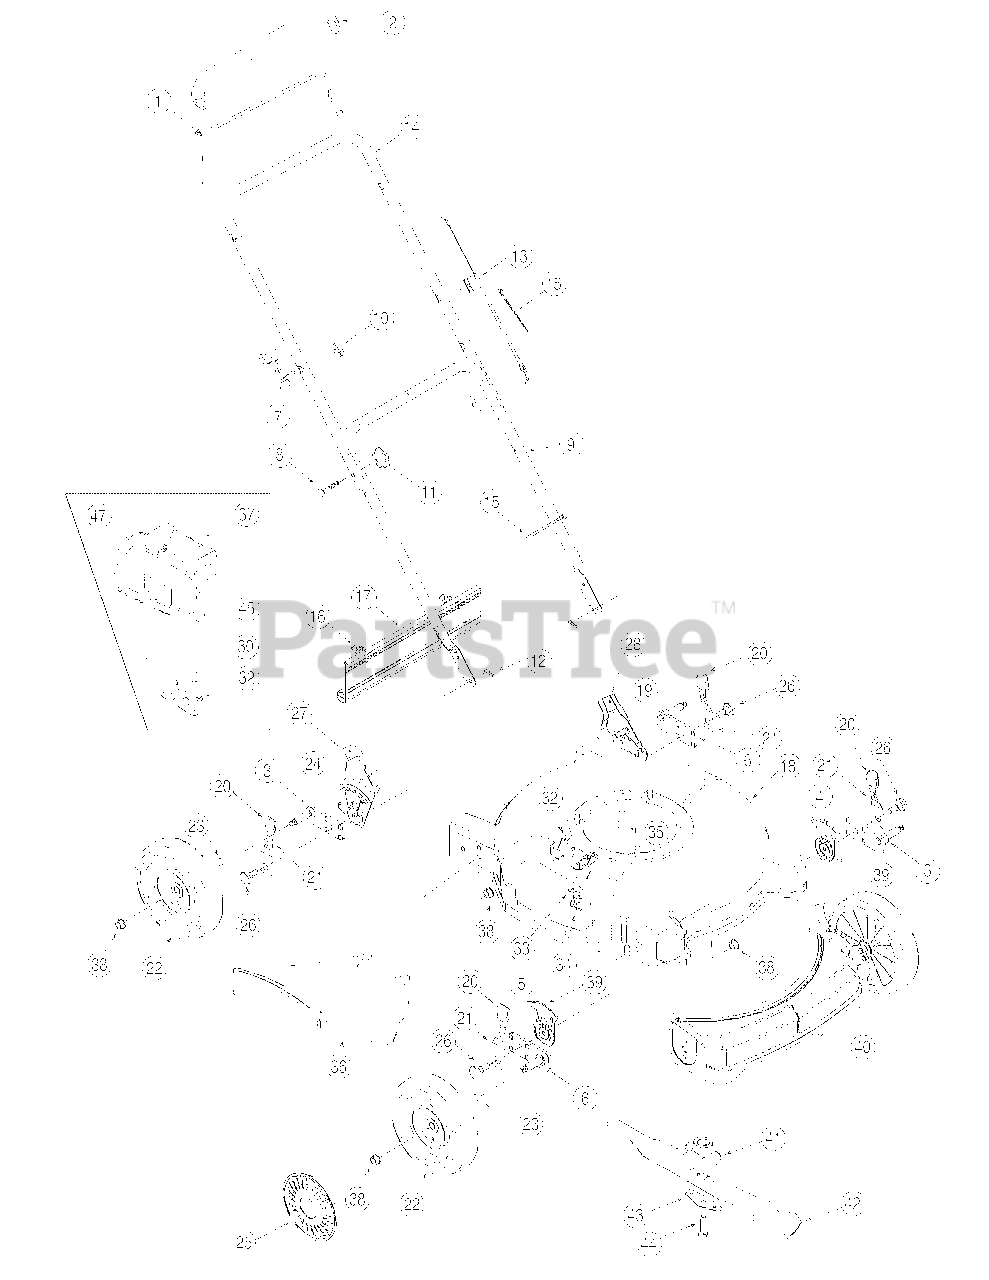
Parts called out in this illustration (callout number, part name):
1	Blade Control Handle
2	Deluxe Cover - Black
3	Pivot Arm LH
4	Hgt. Adjust Ass’y LH
5	Hgt. Adjust Ass’y RH
6	Pivot Arm RH
7	Rope Guide Bolt
8	Carriage Bolt 5/16-18 x 2.0
10	Knob - ERS Guide 1/4-20
11	Knob - Star 5/16-18
12	Int. Cotter Pin .072 x 1.13" Lg.
13	Control Cable 37.25 " Lg. (Honda)
14	Upper Handle
15	Cable Tie
16	Rear Flap
17	Hinge Clip
18	Deck Assembly
19	Rear Hgt. Adjust Ass’y LH
20	Knob
21	Spring Lever
22	Wheel Ass'y 8" x 2.125" Idle BB
23	Wave Washer .51" ID (w/bb wheels)
24	Rear Hgt. Adjust Ass’y RH
25	Hub Cap - Grey (optional)
26	Shoulder Screw .50 Dia. x .385
27	Adjust/Brkt. Ass’y RH
28	Adjust/Brkt. Ass’y LH
30	Torsion Spring
33	Cupped Washer .265 ID x .75 OD
34	Hex Wash S-Tapp Scr 1/4-20 x .50
35	Hex Wash HD Tap Scr 3/8-16 x .88
36	Chute Deflector
37	Mulching Plug
38	Flanged Lock Nut 3/8-16 Gr. F
39	Height Adjuster Plate
